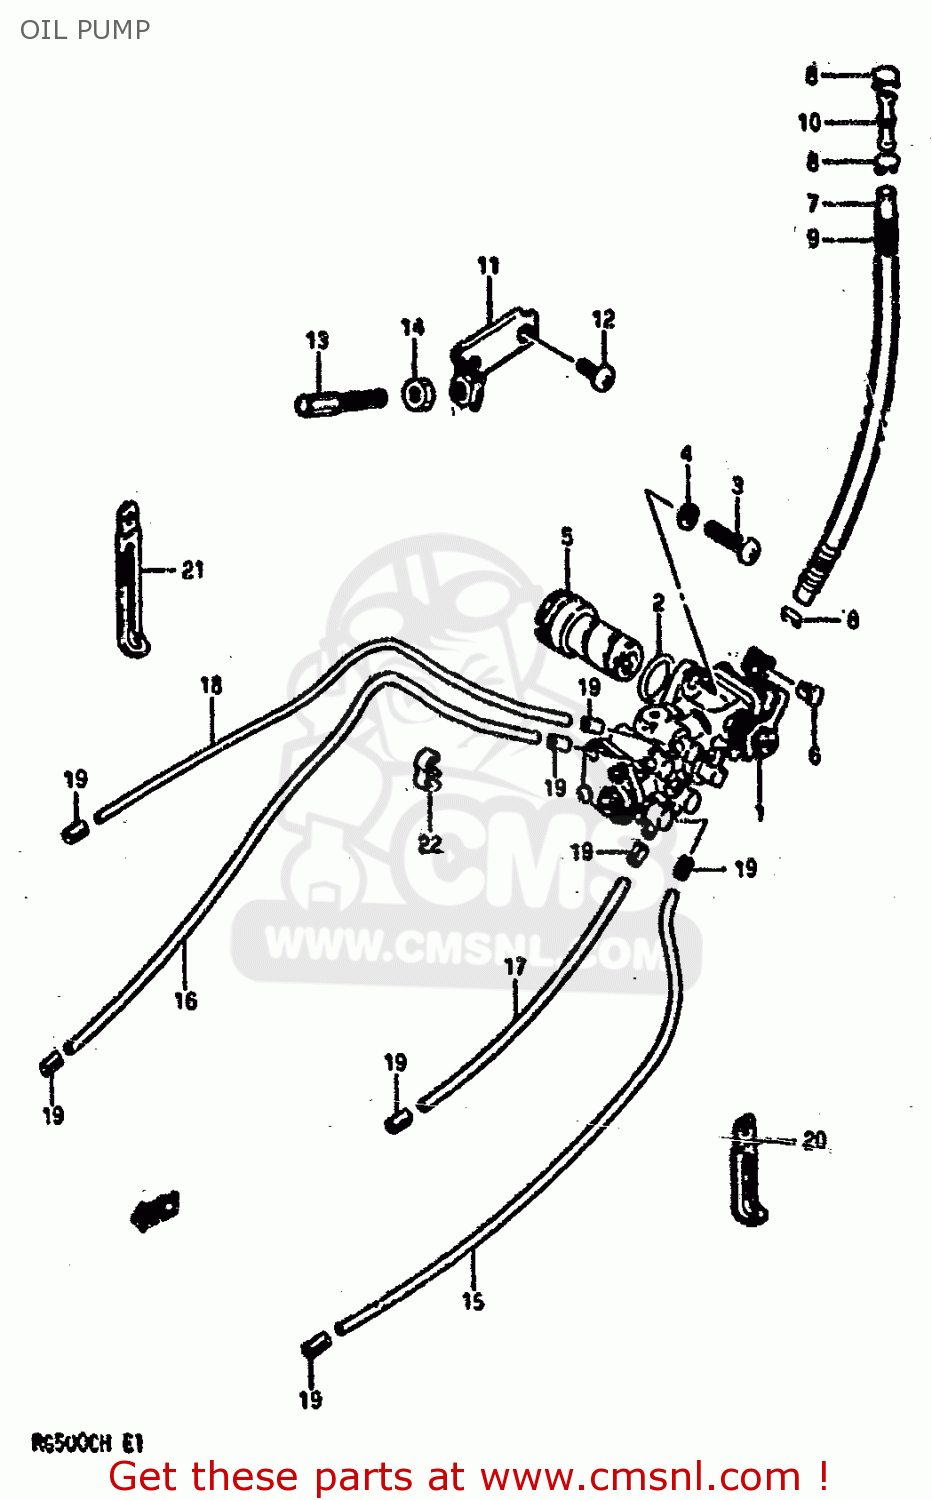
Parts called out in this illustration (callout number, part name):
1	PUMP ASSY,OIL
2	O RING(D:1.5,ID:19.5)
3	SCREW
4	WASHER,LOCK
5	PIECE,OIL PUMP DRIVE
6	TERMINAL,CABLE
7	HOSE
8	CLIP
9	PROTECTOR
10	UNION
11	BRACKET,OIL PUMP CABLE
12	SCREW
13	BOLT
14	NUT
15	HOSE
16	HOSE
17	HOSE
18	HOSE
19	CLIP
20	CLAMP
21	CLAMP
22	CLIP
